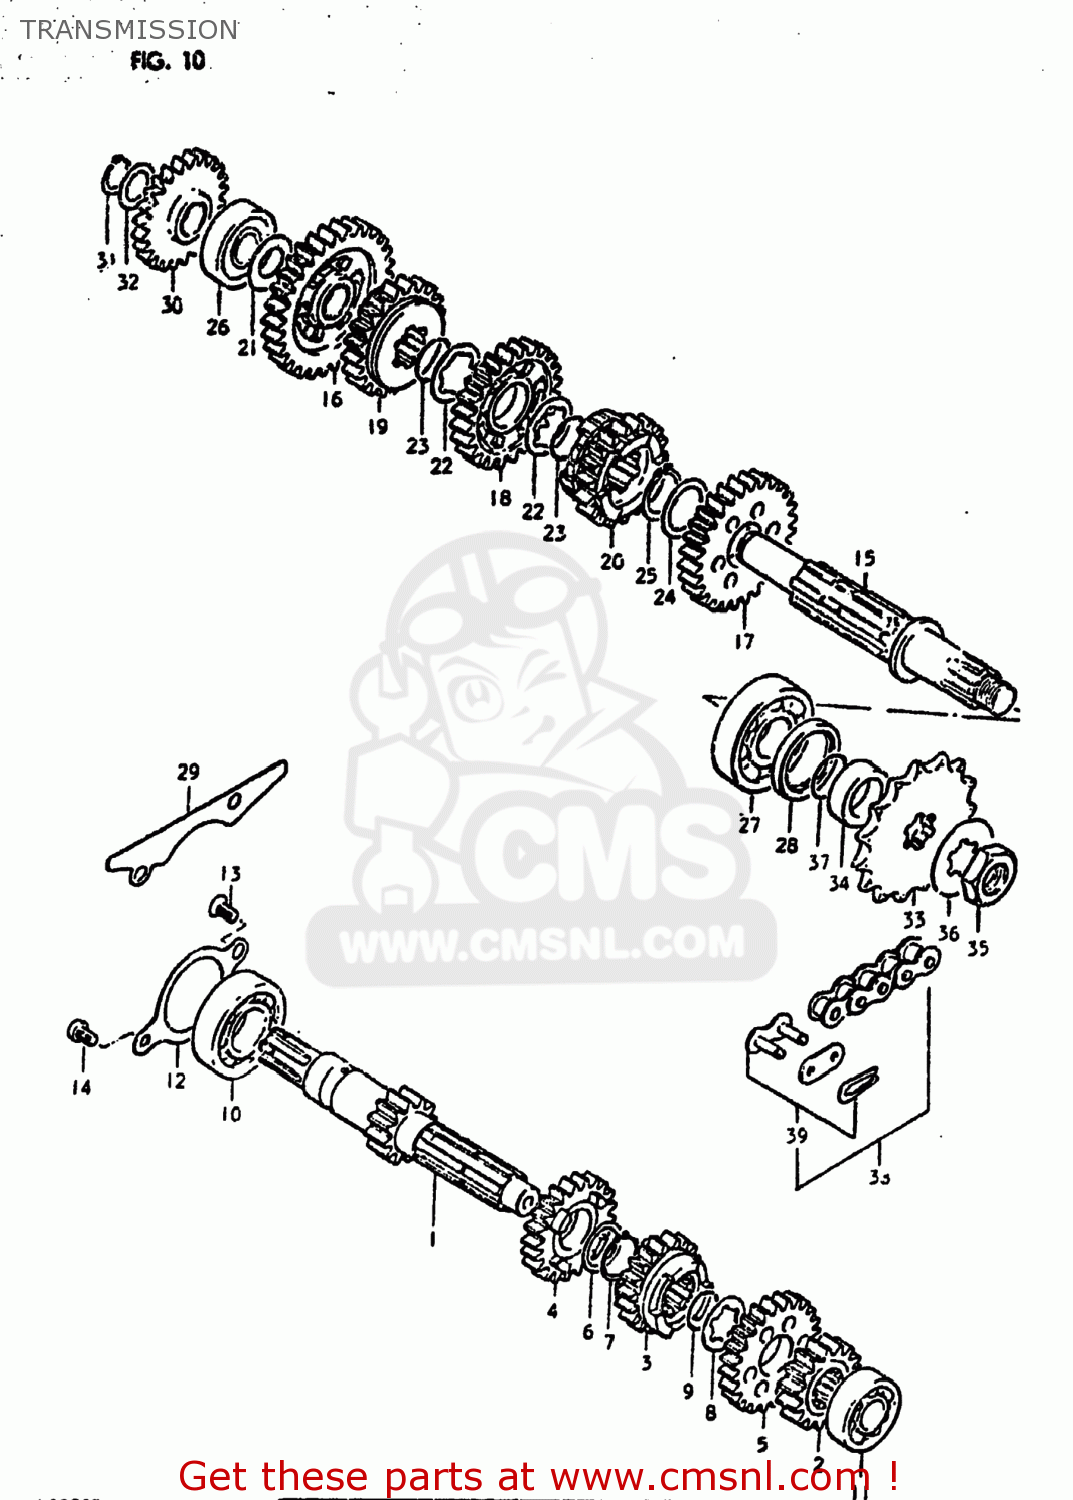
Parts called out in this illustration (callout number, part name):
1	SHAFT,COUNTER
2	GEAR,SECOND DRIVE
3	GEAR,THIRD DRIVE
4	GEAR,FOURTH DRIVE
5	GEAR,FIFTH DRIVE
6	SHIM
7	CIRCLIP
8	WASHER,LOCK
9	CIRCLIP
10	BEARING
11	BEARING
12	PLATE,COUNTERSHAFT BEARING
13	SCREW
14	SCREW 6X12
15	SHAFT,DRIVE
16	GEAR,FIRST DRIVEN
17	GEAR,SECOND DRIVEN
18	GEAR,THIRD DRIVEN
19	GEAR,FOURTH DRIVEN
20	GEAR,5TH DRIVEN
21	WASHER,THRUST
22	WASHER,LOCK
23	RING,SNAP
24	WASHER
25	CIRCLIP
26	BEARING
27	BEARING
28	SEAL,OIL(32X42X6)
29	PLATE,OIL RESERVOIR
30	GEAR,KICK STARTER IDLE
31	CIRCLIP
32	WASHER
33	SPROCKET,ENGINE
34	SPACER(22X32X11.5)
35	NUT
36	WASHER,LOCK
37	O RING(D:1.7,ID:22)
38	CHAIN,DRIVE #525TR-10
39	JOINT ASSEMBLY,CHAIN
